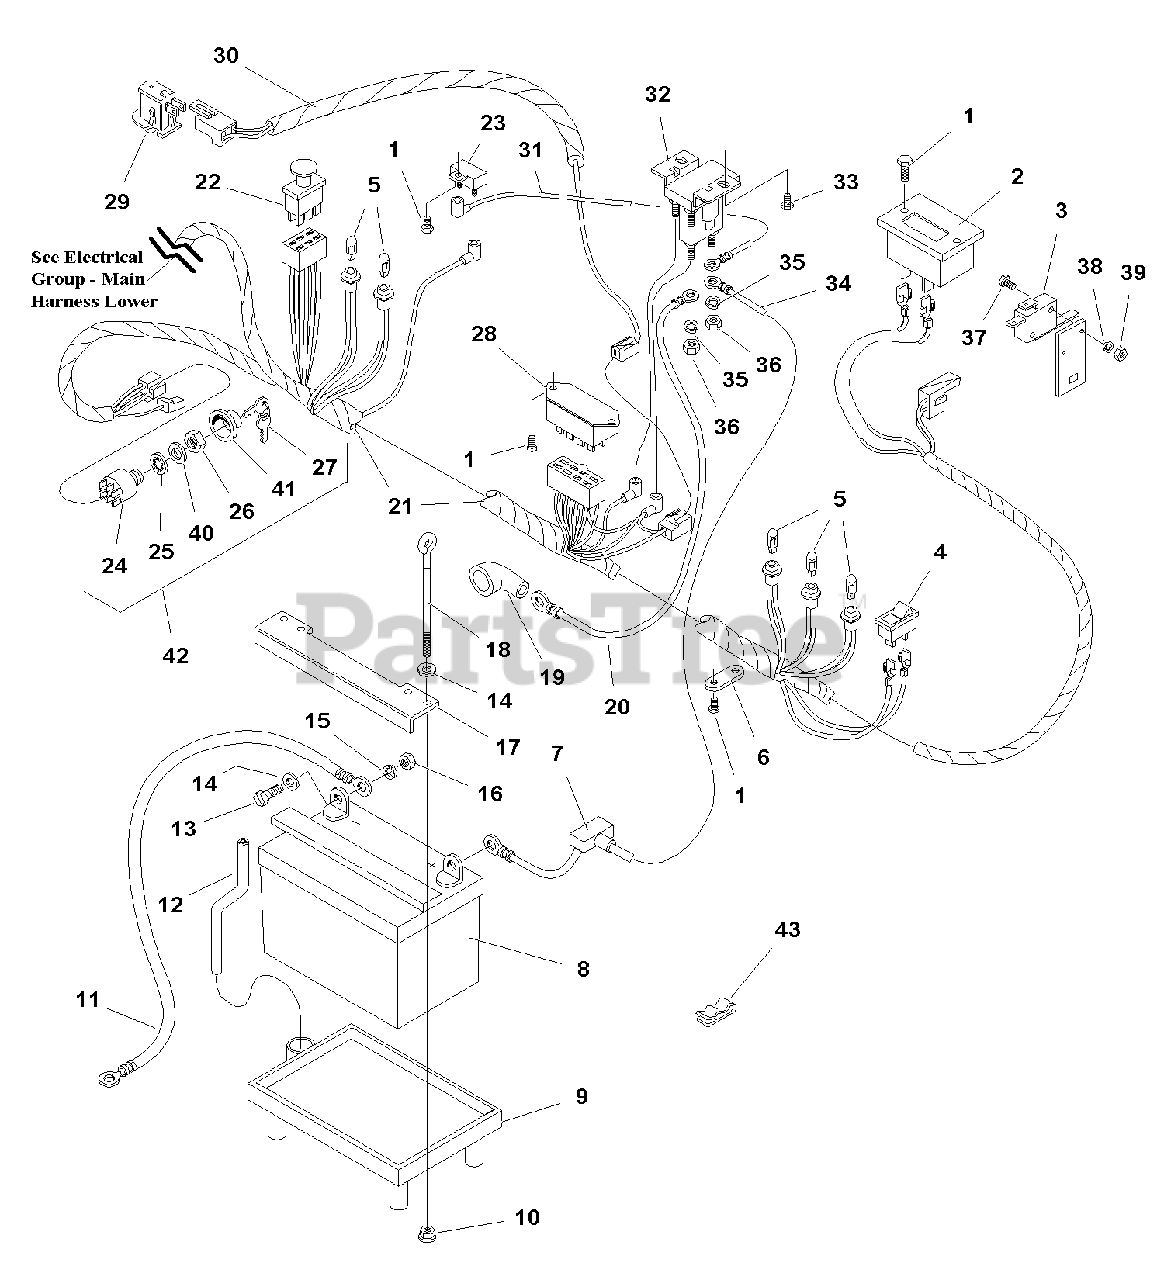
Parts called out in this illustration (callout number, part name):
1	CAPSCREW, Plastite, #8-16 x 1/2
3	INTERLOCK SWITCH, Cruise/Parking Brake
4	SWITCH, Headlight
5	BULB, Indicator Light
6	STRAP, Wire Retainer
7	BOOT, Insulator
9	TRAY, Battery
10	NUT, Plastic, 1/4-20
11	CABLE, Battery to Ground
12	HOSE, Battery, Drain
13	CAPSCREW, Hex Head, 1/4-20 x 3/4
14	WASHER, Plain, 1/4
15	LOCKWASHER, 1/4
16	NUT, Hex, 1/4-20 UNC
17	HOLD DOWN, Battery
18	ROD, Battery Hold Down
19	COVER, Terminal
20	CABLE, Solenoid to Starter
21	WIRE HARNESS, Main (Briggs & Stratton Models)
21	WIRE HARNESS, Main (Kohler Models)
22	SWITCH, PTO Electric Clutch
23	CIRCUIT BREAKER
24	IGNITION SWITCH, 6-Pin, Steel Body
25	LOCKWASHER, Internal
26	NUT, Hex, Flange
27	KEY, Ignition, Set of 2
29	SWITCH, Clutch Brake Pedal
30	WIRE ASSEMBLY, Clutch Brake Pedal
31	WIRE ASSEMBLY, Circut Breaker to Solenoid
32	SOLENOID
33	CAPSCREW, Hex Washer Head, Plastite, 1/4-20 x 1/2
34	CABLE, Battery to Solenoid
35	LOCKWASHER, 5/16
36	NUT, Hex, 5/16-24
37	CAPSCREW, Taptite, #5-40 x 3/4
38	LOCKWASHER, 1/8
39	NUT, Machine Screw, #5-40
40	WASHER, 5/8 x 1
41	COVER, Ignition Switch
42	IGNITION SWITCH KIT (Includes Ref. Nos. 24, 25, 26, 27, 40, 41)
43	CLIP
